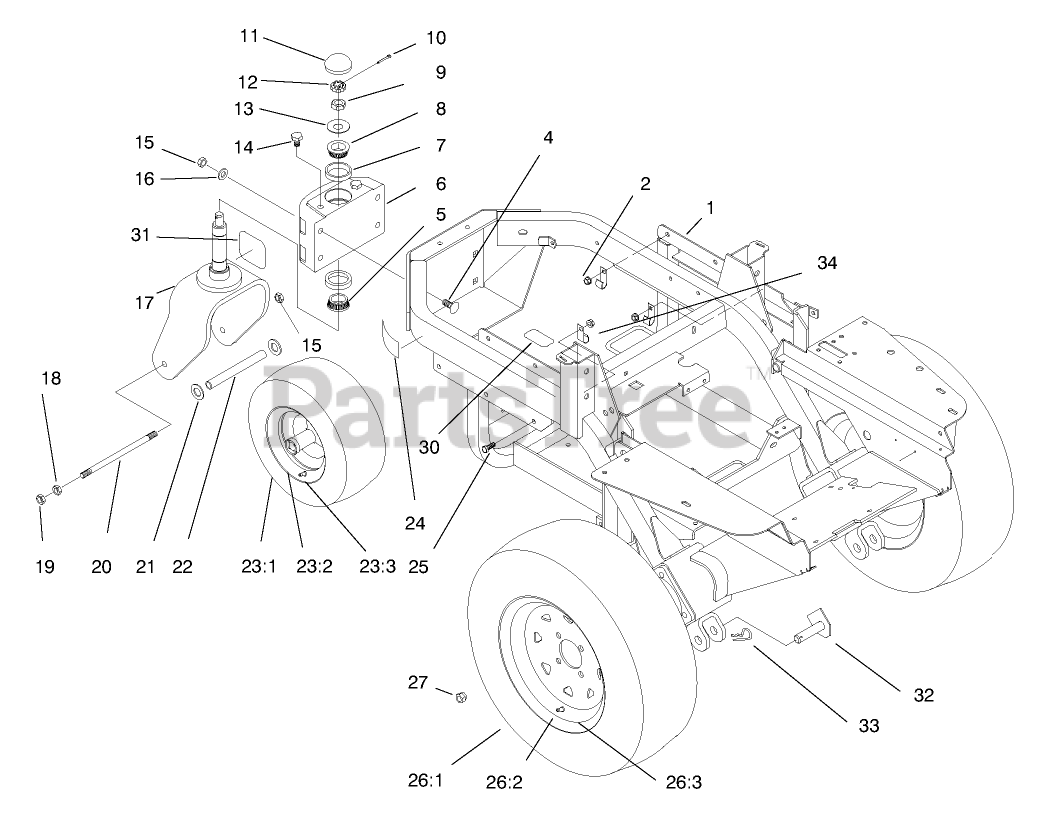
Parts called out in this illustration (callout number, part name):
1	ENGINE SUPPORT ASM
2	NUT-LOCK, NI
3	FRAME ASM W/ DECALS
4	SCREW-CARR
5	BEARING-CONE
6	HOUSING - SPINDLE
7	CUP-BEARING, ROLLER
8	BEARING-ROLLER, CONE
9	NUT-JAM
10	PIN-COTTER
11	DUSTCAP
12	NUT-LOCK, RETAINER
13	WASHER-FLAT
14	SCREW-HH
15	NUT-LOCK, NI
16	WASHER-FLAT
17	CASTER FORK ASM
18	NUT-HH
19	NUT-JAM
20	AXLE - CASTOR
21	WASHER-FLAT
22	TUBE-SPACER, CASTOR
23:2	WHEEL
24	DECAL-HOT SURFACE
25	SCREW-HH
26:1	TIRE
26:2	STEM-VALVE
26:3	WHEEL
27	NUT-LUG
28	RIVET-BLIND
30	DECAL-WARNING
31	DECAL - Z320
32	PIVOT PIN ASM
33	PIN-HAIR
34	CLIP
